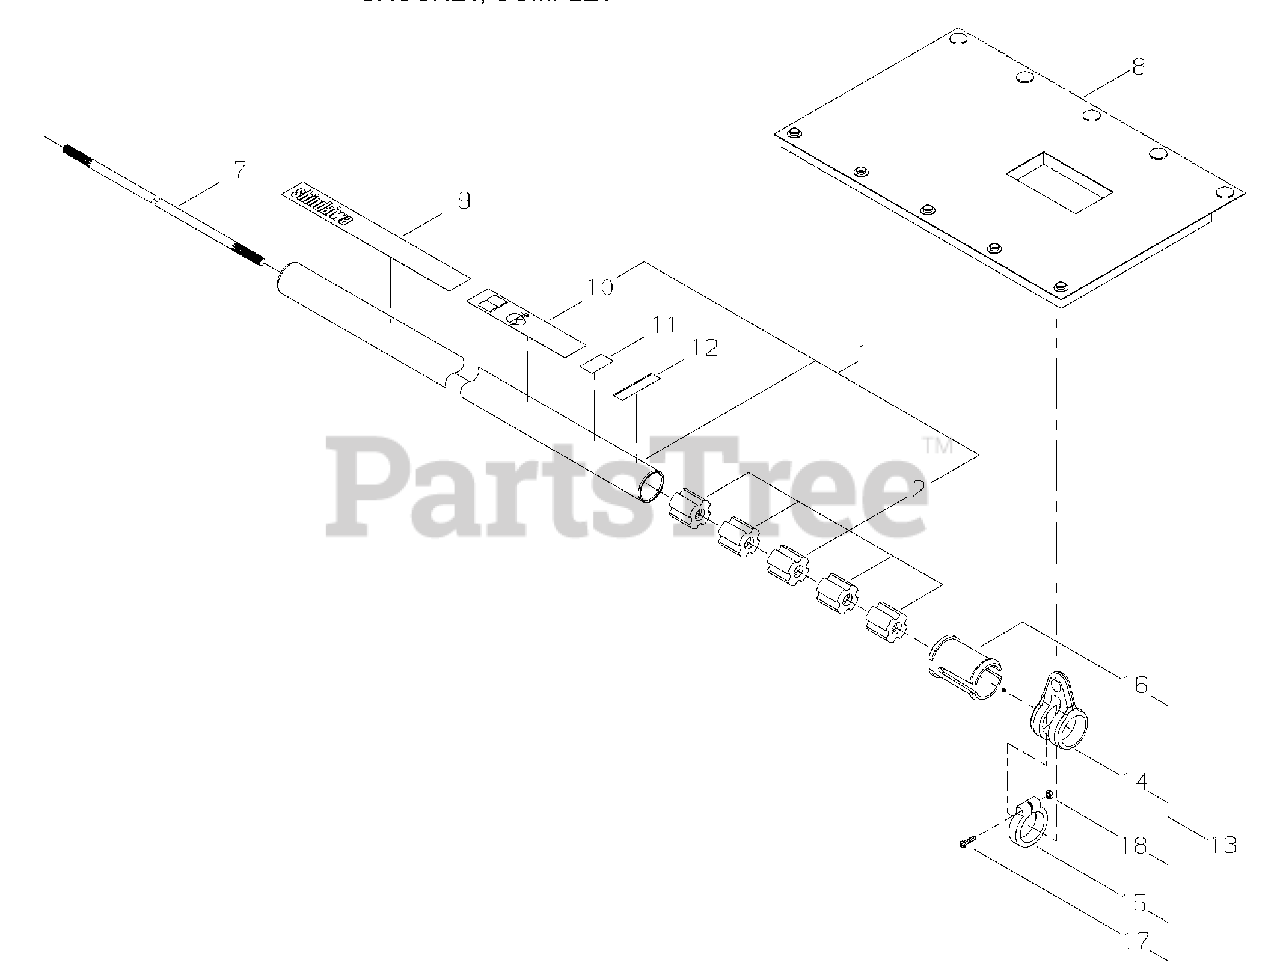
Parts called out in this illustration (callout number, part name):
1	MAIN PIPE ASSY
2	BUSHING
7	PIPE, MAIN
8	SLEEVE, PROTECTOR
9	LABEL - TRADE
10	LABEL - CAUTION
11	LABEL - INSTRUCTION
12	LABEL - HANDLE LOCATION
13	HANGER ASSY
14	HANGER
15	CLAMP
16	COLLAR
17	SCREW - 4X16
18	NUT - 4
